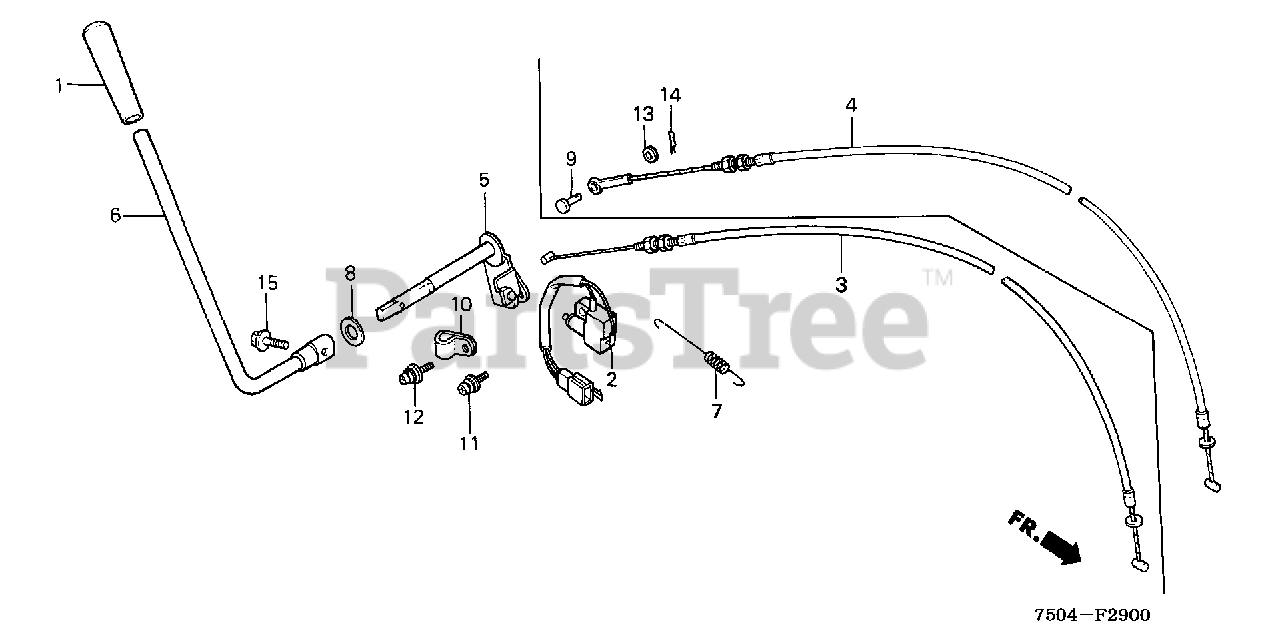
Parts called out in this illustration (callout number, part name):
1	GRIP, CHANGE LEVER
2	SWITCH ASSY., P.T.O. CLUTCH
4	CABLE, P.T.O. CLUTCH
5	ARM, P.T.O. CLUTCH LEVER
6	LEVER, P.T.O. CLUTCH
7	SPRING, P.T.O. CLUTCH
8	WASHER, PLAIN (12MM)
9	PIN, AUXILIARY CHANGE LEVER JOINT
10	CLIP, WIRE HARNESS
11	SCREW-WASHER (4X12)
12	SCREW-WASHER (4X14)
13	WASHER, PLAIN (6MM)
14	PIN, LOCK (6MM)
15	BOLT, FLANGE (6X12)
